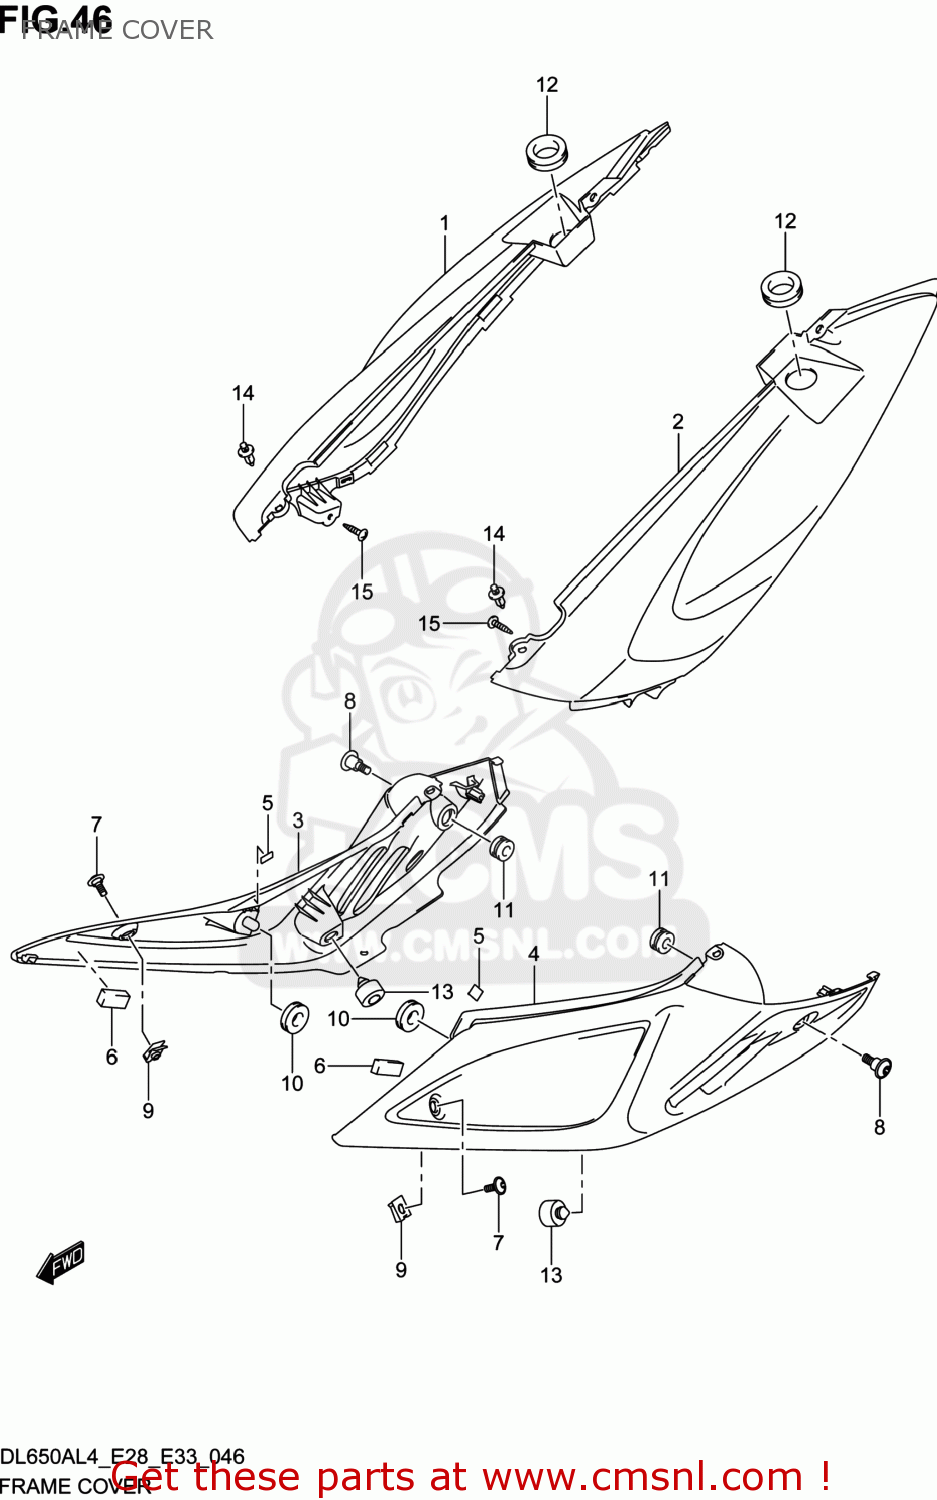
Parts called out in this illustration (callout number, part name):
1	COVER,FRAME,R(RED)
2	COVER,FRAME,L(RED)
3	COVER,FRAME SIDE,R
4	COVER,FRAME SIDE,L
5	CUSHION,RR COVER NO.2
6	CUSHION
7	BOLT(5X13)
8	BOLT(6X20)
9	NUT
10	CUSHION
11	CUSHION
12	CUSHION
13	CUSHION
14	CLIP(BLACK)
15	SCREW
